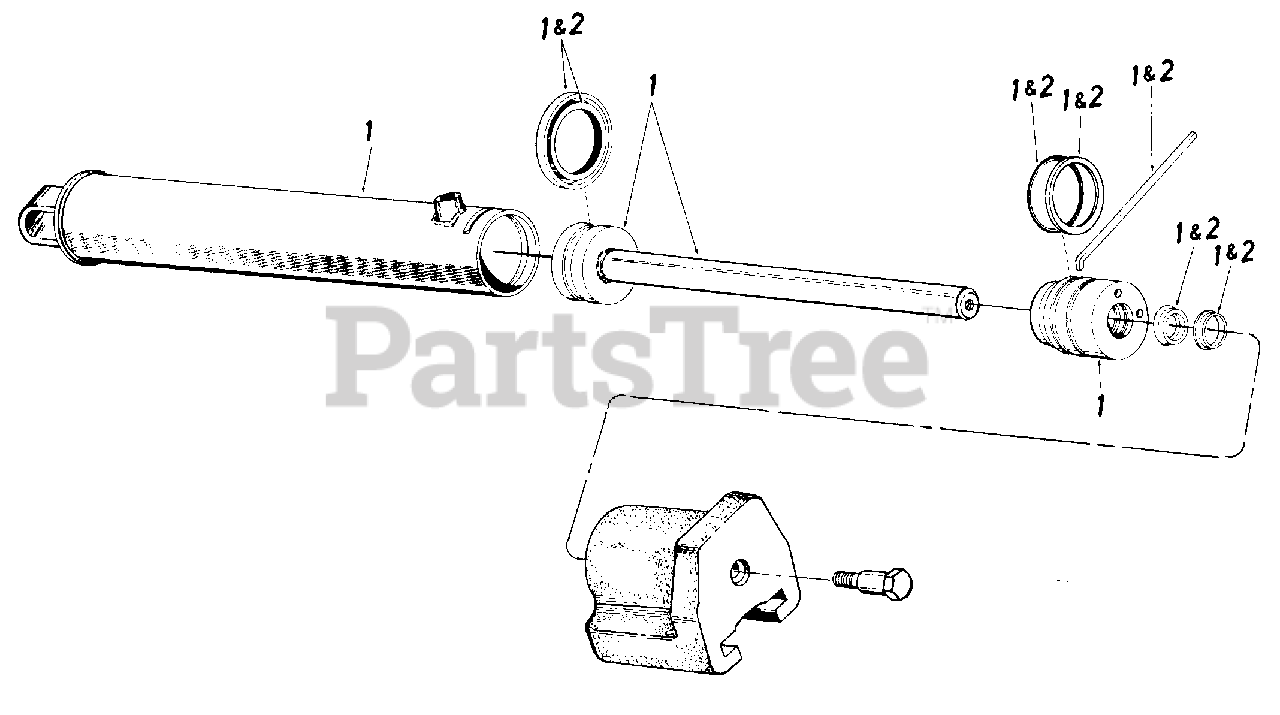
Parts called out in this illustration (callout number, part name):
1	Cylinder Ass'y. Comp.
1	Cylinder Ass'y. Comp
2	3-1/2" Cyl. Kit "O"-Ring Set
2	4" Cyl. Kit "O"-Ring Set
